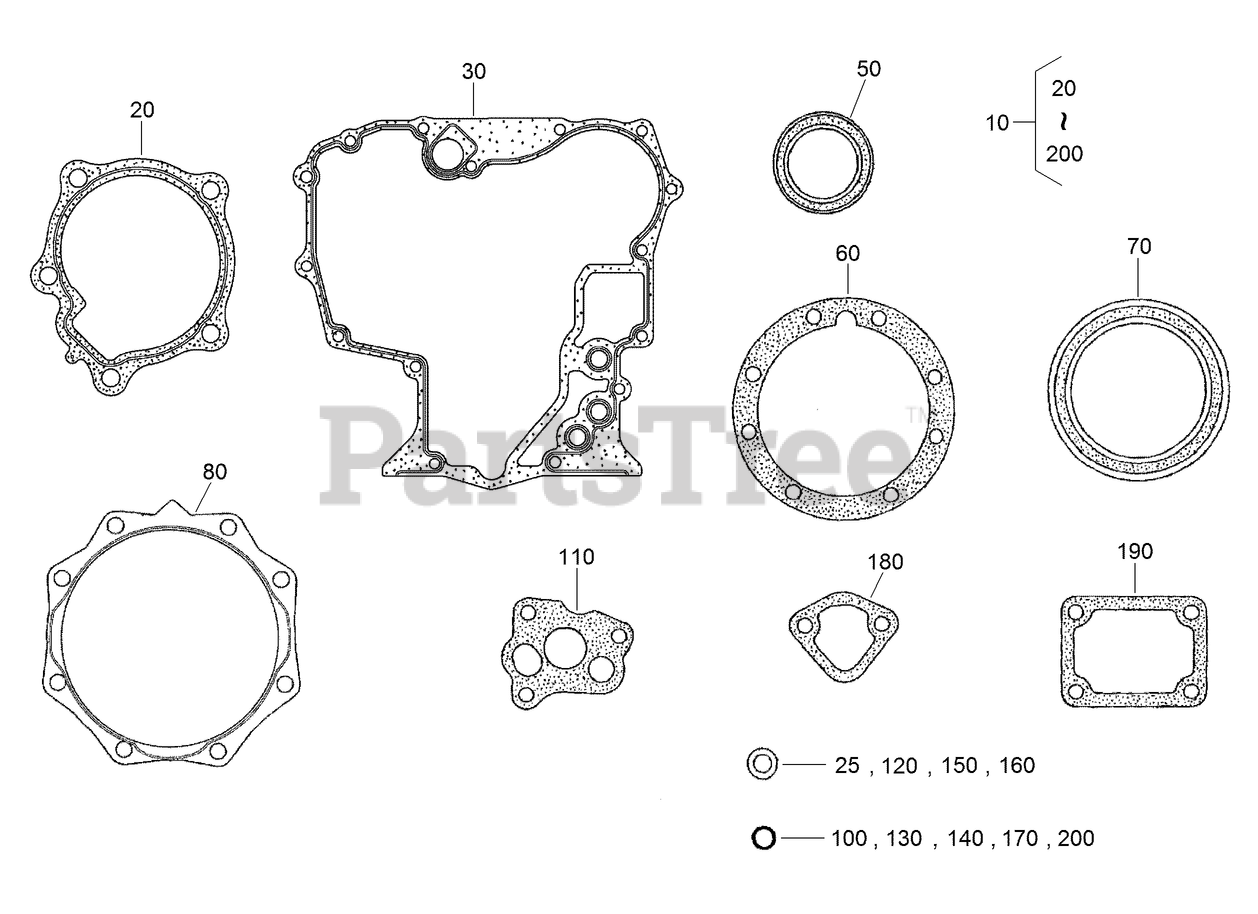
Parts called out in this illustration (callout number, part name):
10	LOWER GASKET KIT
20	GASKET-PUMP, WATER
25	GASKET
30	GASKET-CASE, GEAR
50	SEAL-OIL
60	GASKET-CASE, BEARING
70	SEAL-OIL
80	GASKET-COVER, CASE
100	O-RING
110	GASKET-PUMP, OIL
120	GASKET
130	O-RING
140	O-RING
150	GASKET
160	GASKET-PAN, OIL
170	O-RING
180	GASKET-PUMP, FUEL
190	GASKET-PLATE, CONTROL
200	O-RING
